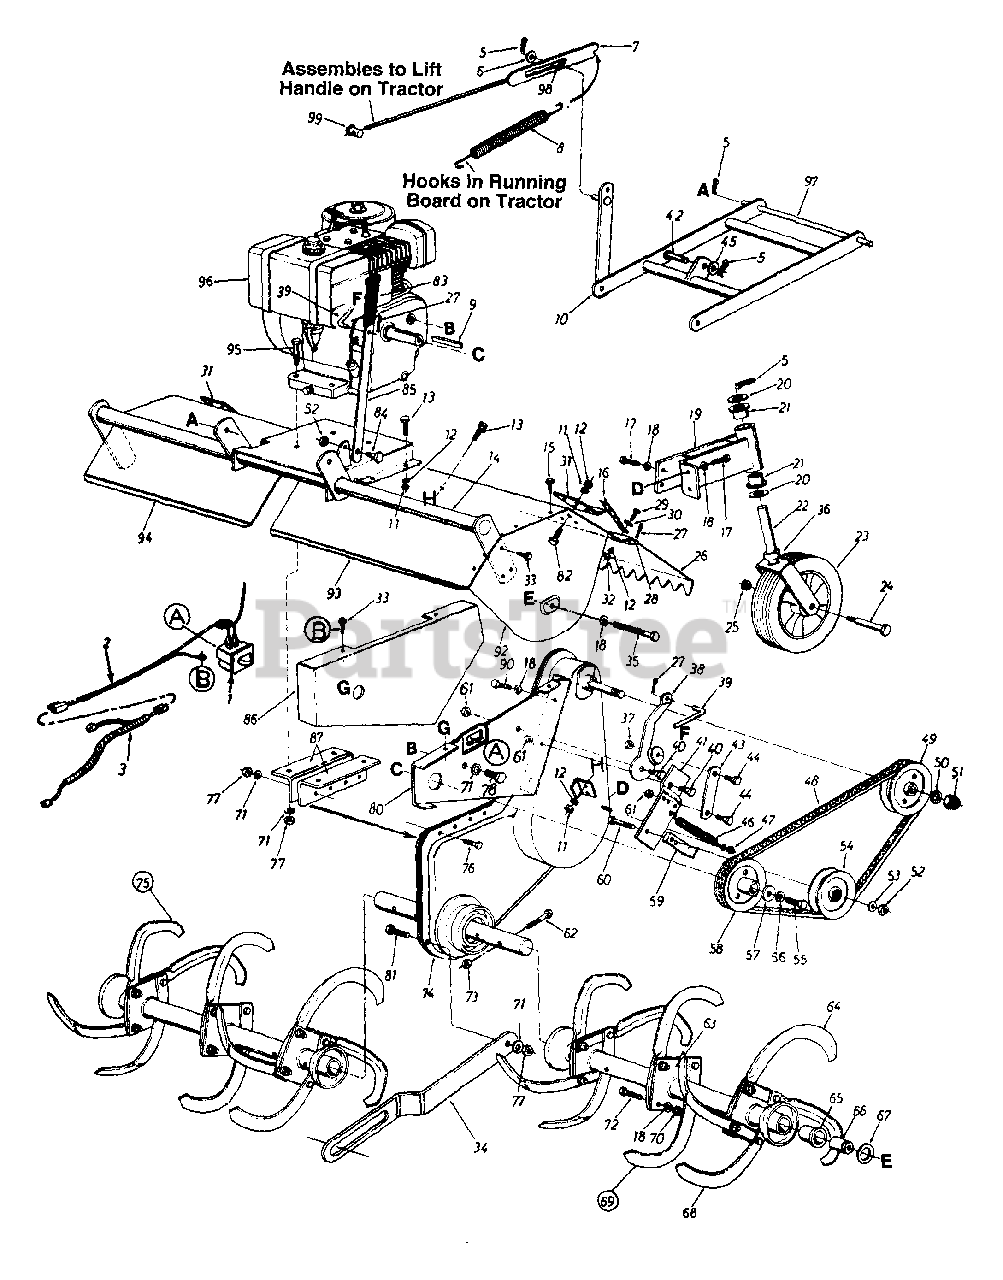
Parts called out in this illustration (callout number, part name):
1	Safety Switch
2	Wire Harness
3	Adapter Harness
5	Internal Cotter Pin
6	Fl-Wash. 1/2" I.D. x .93" O.D.
9	Sq. Key 1/4" x 1/4" x 2.00" Lg.
12	L-Wash. 1/4" I.D.
13	Hex Bolt 1/4-28 x .62" Lg.
16	#2 Dog Chain x 20" Lg.
17	Hex Wash. Hd. Self-Tap Scr. 3/8-24 x .75" Lg.
18	L-Wash. 3/8" I.D.
19	Swivel Wheel Support
20	Fl-Wash. 3/4" I.D. x 1.50" O.D.
21	Flange Bearing 3/4" I.D. x 1.00" O.D.
22	Swivel Wheel Caster
23	Wheel Assembly 10.0 x 2.75
24	Shoulder Bolt.623" I.D. x 3.62" Lg.
25	Hex Cent. L-Nut 7/16-14 Thd.
28	L.H. Flap Rod
28	R.H. Flap Rod
29	Hex Bolt 1/4-20 x .62" Lg.
30	Fl-Wash. 1/4" I.D.
33	Hex Wash. Hd. Self-Tap Scr. 1/4" x .62" Lg.
34	Stabilizer Link
35	Hex Bolt 3/8-16 x 1.25" Lg.
36	Spacer .752" I.D. x 1.25" O.D.
37	Hex Cent. L-Nut 5/16-18 Thd.
40	Shoulder Bolt 7/16" Dia. x 1.75"
45	Fl-Wash. .50" I.D. x 1.0" O.D. x .06
46	Extension Spring .62" O.D. x 6.12" Lg.
47	Hex Crown Nut 3/8-24 Thd.
48	V-Belt (Kevlar)
49	1/2" "V"-Pulley 4.75" O.D. x .625" Bore
50	L-Wash. 5/8" I.D.
51	Hex Ins. L-Nut 5/18-16 Thd.
52	Hex Cent. L-Nut 3/8-16 Thd.
53	Fl-Wash. 3/8" I.D.
54	Idler Pulley 4.0" O.D.
55	Hex Bolt 7/16-20 x 1" Lg.
56	L-Wash. 7/16" I.D.
57	Fl-Wash. 7/16" I.D. x 1.38"
58	1/2" "V"-Pulley .475" O.D. x 1.00" Bore
61	Hex Cent. L-Nut 5/16-18 Thd.
62	Hex Bolt 7/16-14 x 2.00" Lg.
65	Flange Bearing 1.00" I.D.
66	Spacer
67	Thrust Wash. 1/2" I.D. x 1.55"
68	Tine - R.H.
69	Tine Assembly Comp.- L.H.
70	Hex Nut 3/8-24 Thd.
71	L-Wash. 5/16" I.D.
72	Hex Bolt 3/8-24 x 1.5" Lg.
73	Hex Cent. L-Nut 7/16-14 Thd.
77	Hex Nut 5/16-18 Thd.
78	Hex Bolt 5/16-24 x .62"
80	Clutch Support Bracket
81	Shld. Bolt .435" Dia. x .265" 5/16-18 Thd.
82	Hex Bolt 1/4-28 x .75" Lg.
83	Plastic Grip
84	Shoulder Bolt .498" Dia. x .212" Lg.
87	Engine Mounting Bracket
90	Hex Bolt 3/8-16 x .62" Lg.
92	L.H.- Side Plate
96	8 H.P. Engine
97	Hitch Rod
98	Push Bar Sleeve .503" I.D. x .624" O.D.
99	Ferrule
